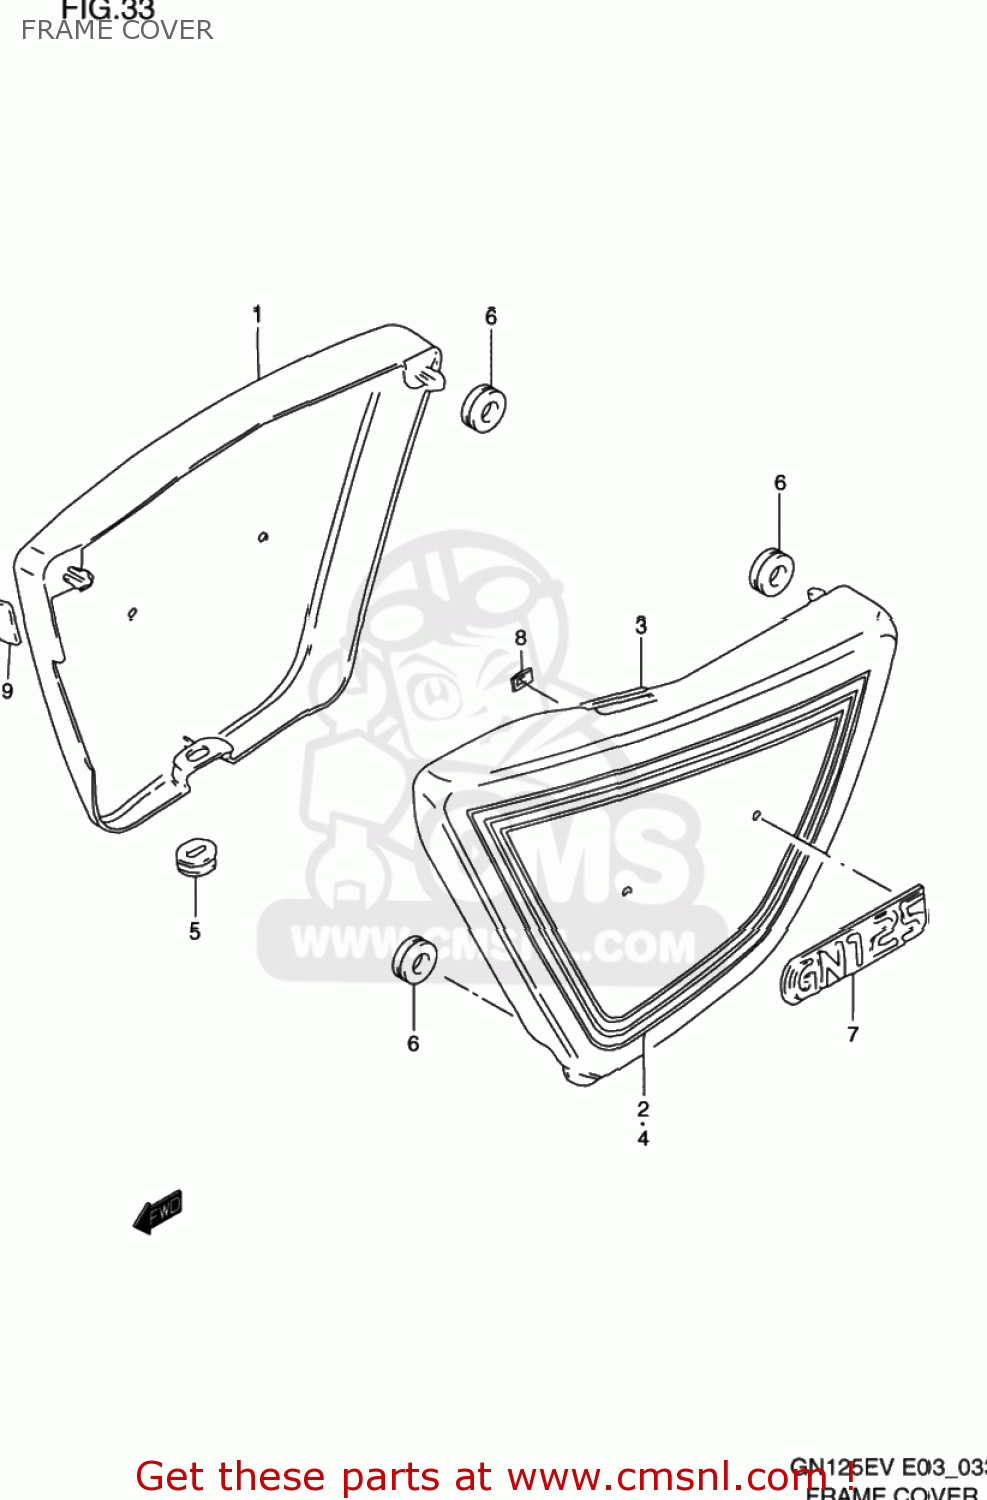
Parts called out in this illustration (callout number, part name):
1	COVER,FRAME,RIGHT (RED)
2	TAPE SET,FRAME COVER,R
3	C0VER,FRAME,L(RED)
4	TAPE SET,FRAME COVER,L
5	CUSHION
6	CUSHION
7	EMBLEM,FRAME COVER
8	NUT
9	PROTECTOR(12X40)
